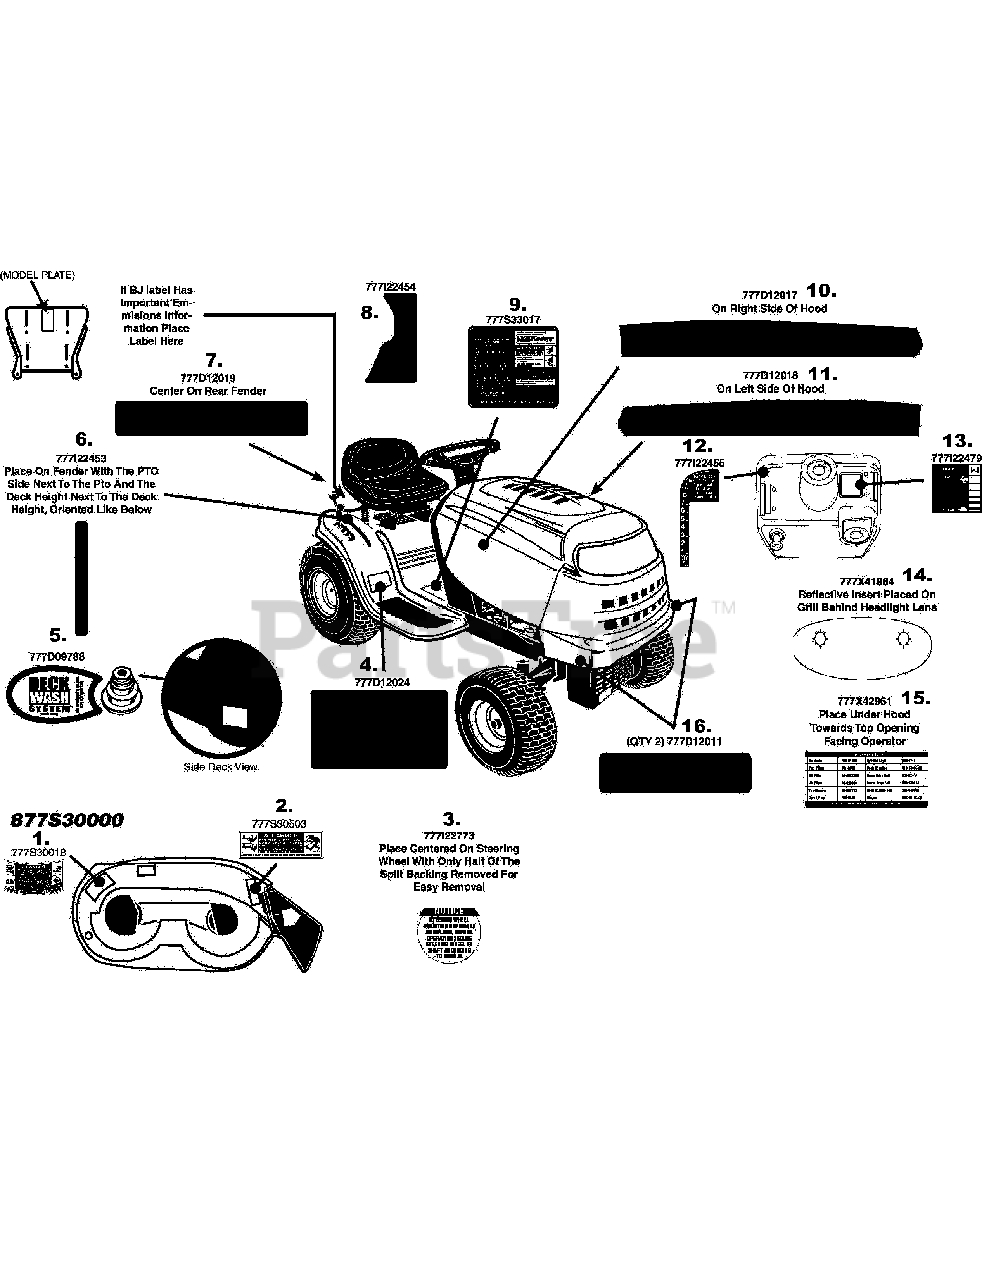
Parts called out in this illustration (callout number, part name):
1	LABEL-DECK SAFETY
2	LABEL-DANGER CHUTE
3	LABEL-RIDER:SECURE WHEEL
4	LABEL-RIDER FENDER 42" 7 SPD
5	LABEL:RIDER:WHITE
6	LABEL:RIDER LT-5 FENDER
7	LABEL-RIDER REAR FENDER MTD GOLD
8	LABEL:RIDER LT-5 FENDER
9	LABEL-LT 5 TRANS COVER NO OCR
10	LABEL-RIDER HOOD MTD GOLD RH
11	LABEL-RIDER HOOD MTD GOLD LH
12	LABEL:RIDER LT-5 DASH
13	LABEL: RIDER LT-5 THRT/CHK
14	LABEL:RIDER 1&5 STYLE GRILL
15	LABEL-RIDER PARTS LABEL J771G204
16	LABEL-RIDER LOWER GRILLE CAST IRON
